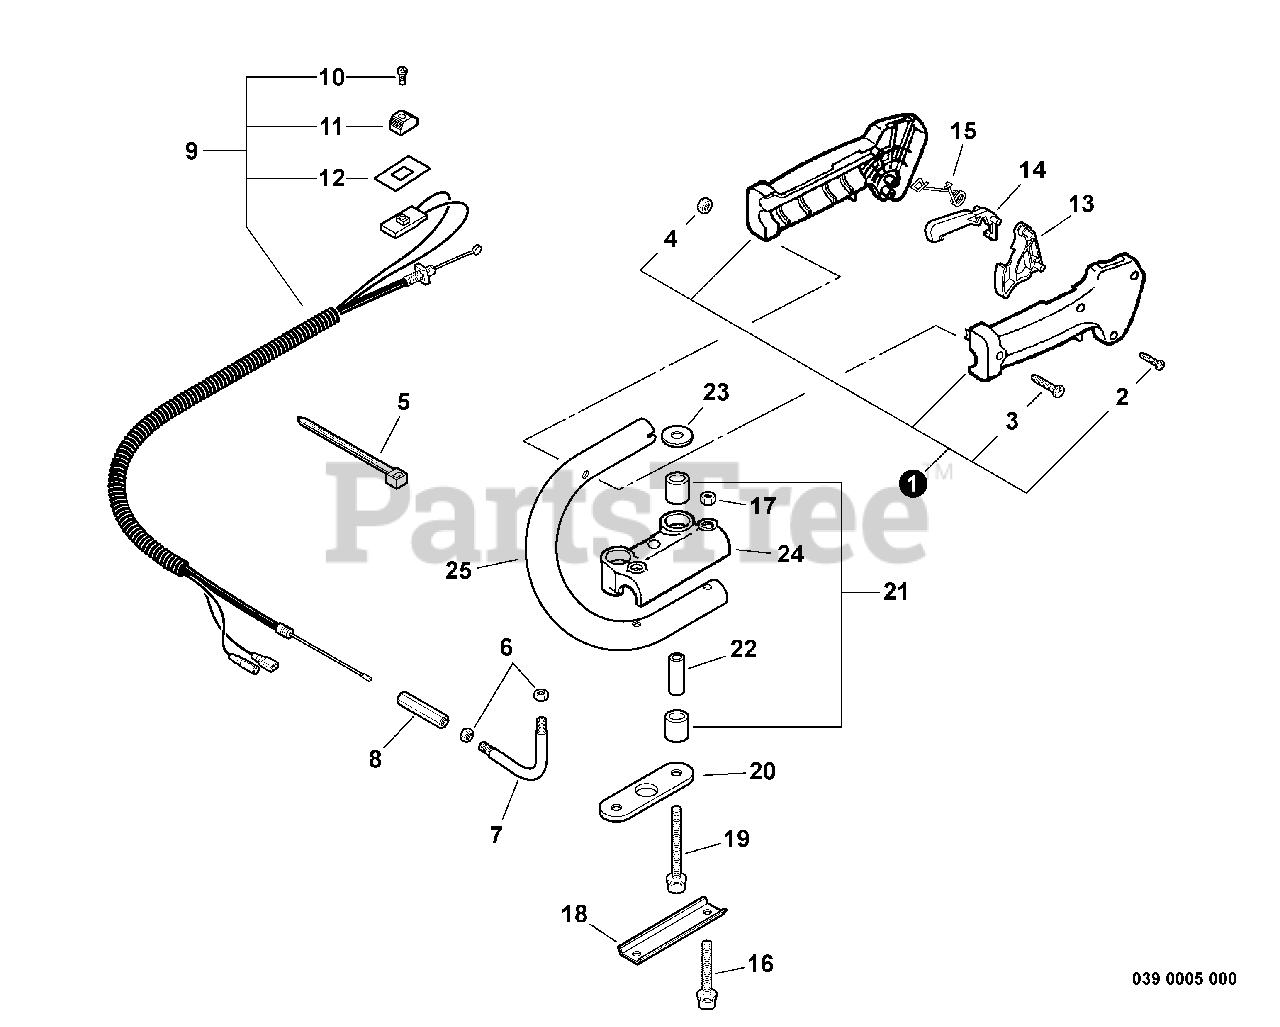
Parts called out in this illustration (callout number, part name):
1	CONTROL HANDLE KIT
2	SCREW 3×25
3	SCREW 5×30
4	NUT M5
5	STRAP, TIE
6	NUT 3N-7
7	TUBE, THROTTLE CABLE
8	CONNECTOR
9	CABLE ASSY, CONTROL
10	SCREW 3×10
11	KNOB, SWITCH - ORANGE
12	LABEL, SWITCH
13	TRIGGER, THROTTLE
14	LOCKOUT, THROTTLE
15	SPRING, TORSION
16	BOLT M5×35
17	NUT M5
19	BOLT 5×45
20	PLATE, EYE
22	SPACER
23	WASHER 5.5×18×1
24	BRACKET, HANDLE - UPPER
25	HANDLE, REAR
